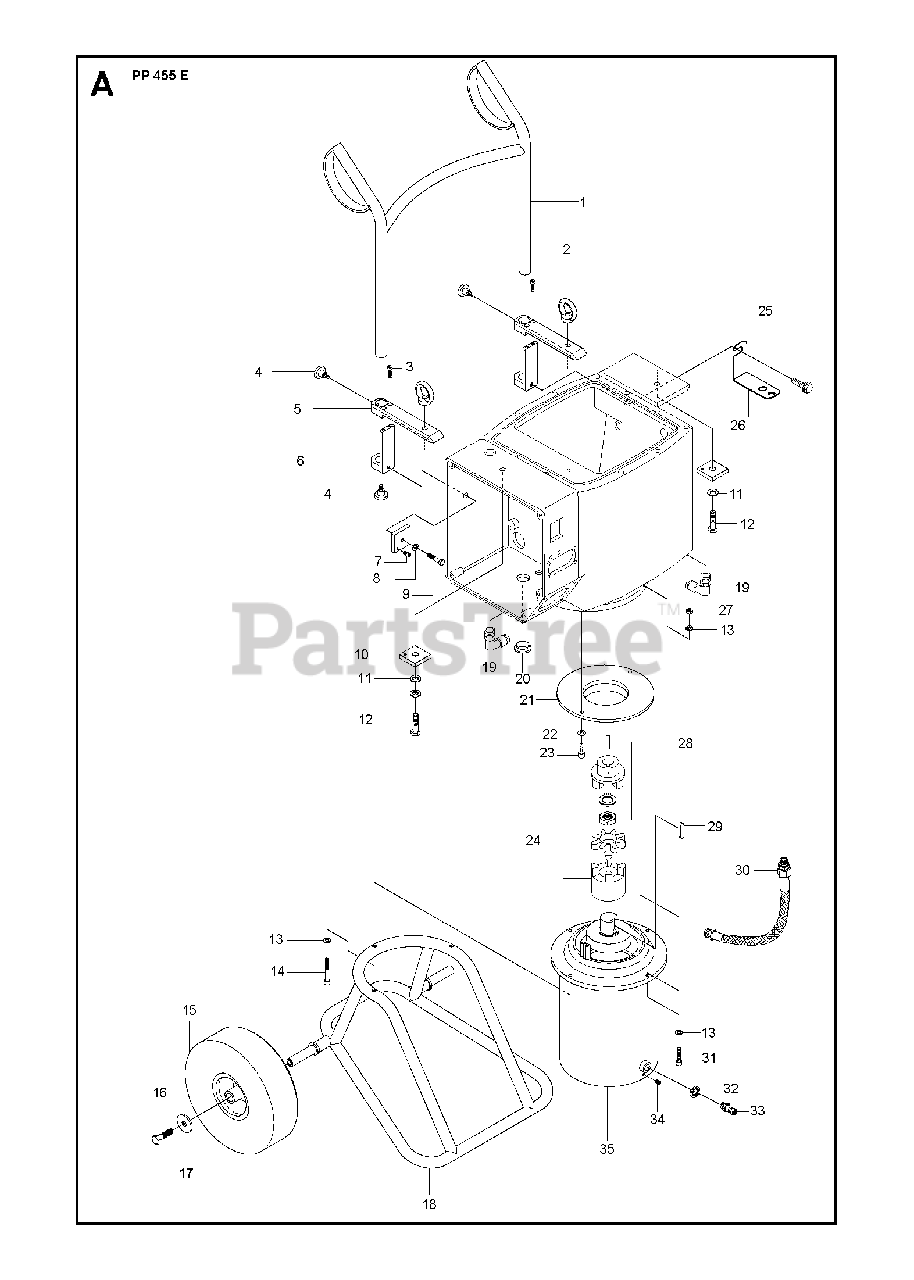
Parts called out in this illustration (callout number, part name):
3	SCREW IHSCM
13	WASHER
27	HEXAGON NUT
32	SEALING WASHER
35	ELECTRIC BOX230V
35	ELECTRIC MOTOR575V
35	ELECTRIC BOX400V
